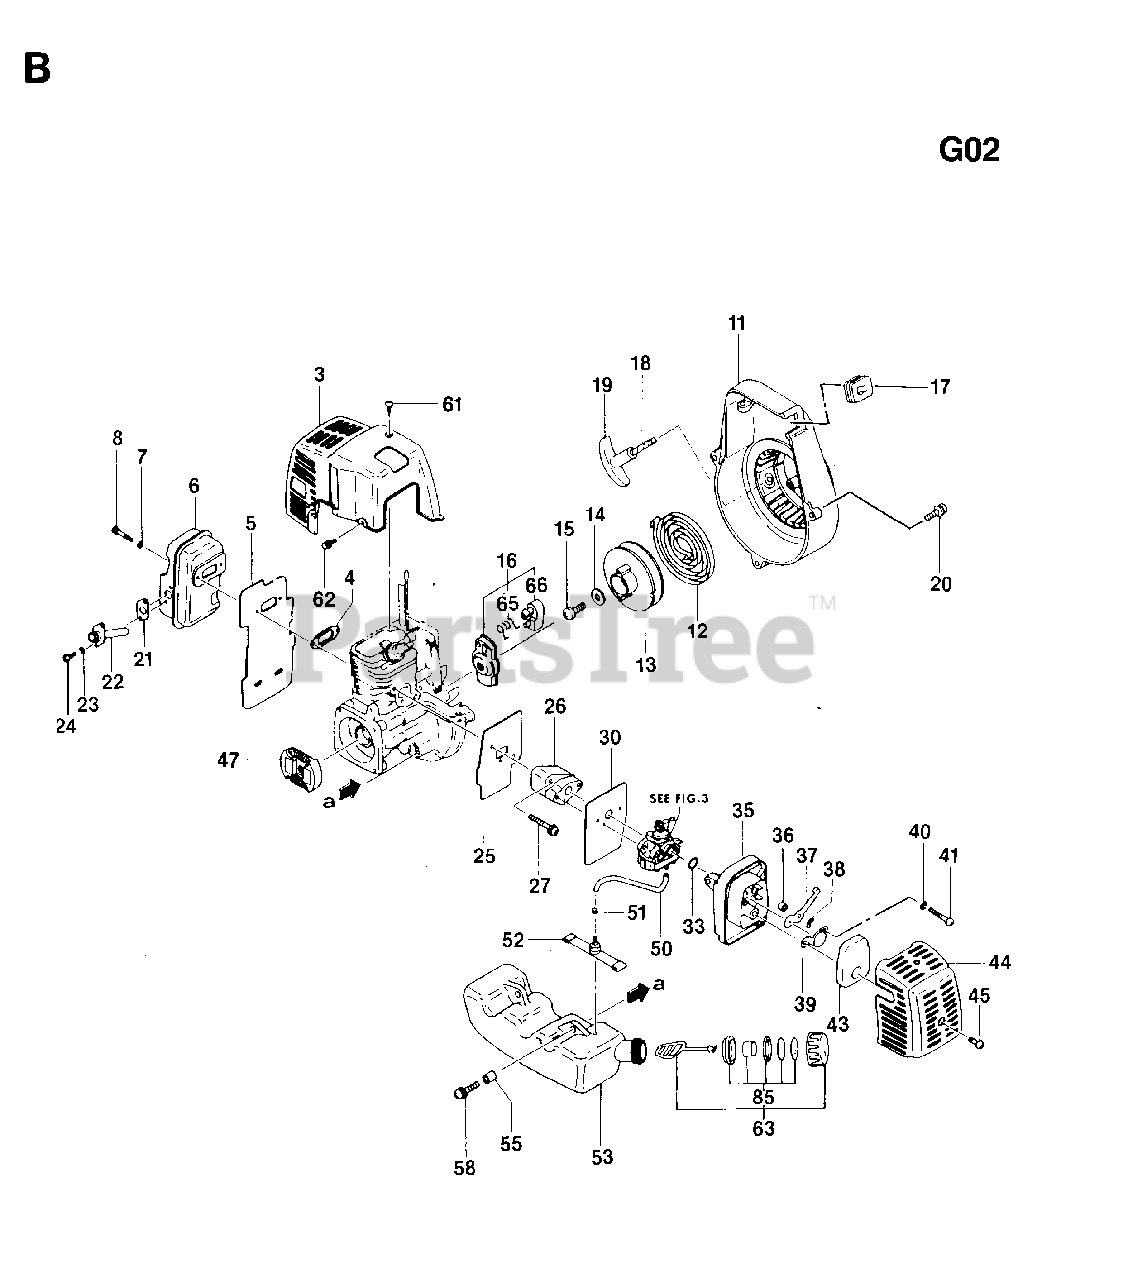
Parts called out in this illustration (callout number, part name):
7	WASHER 5.3X12
8	SCREW MC6S 5X50
23	SPRING WASHER 4.1X7.1
24	SCREW MC6S 4X8
40	SPRING WASHER
41	SCREW MC6S 5X60
